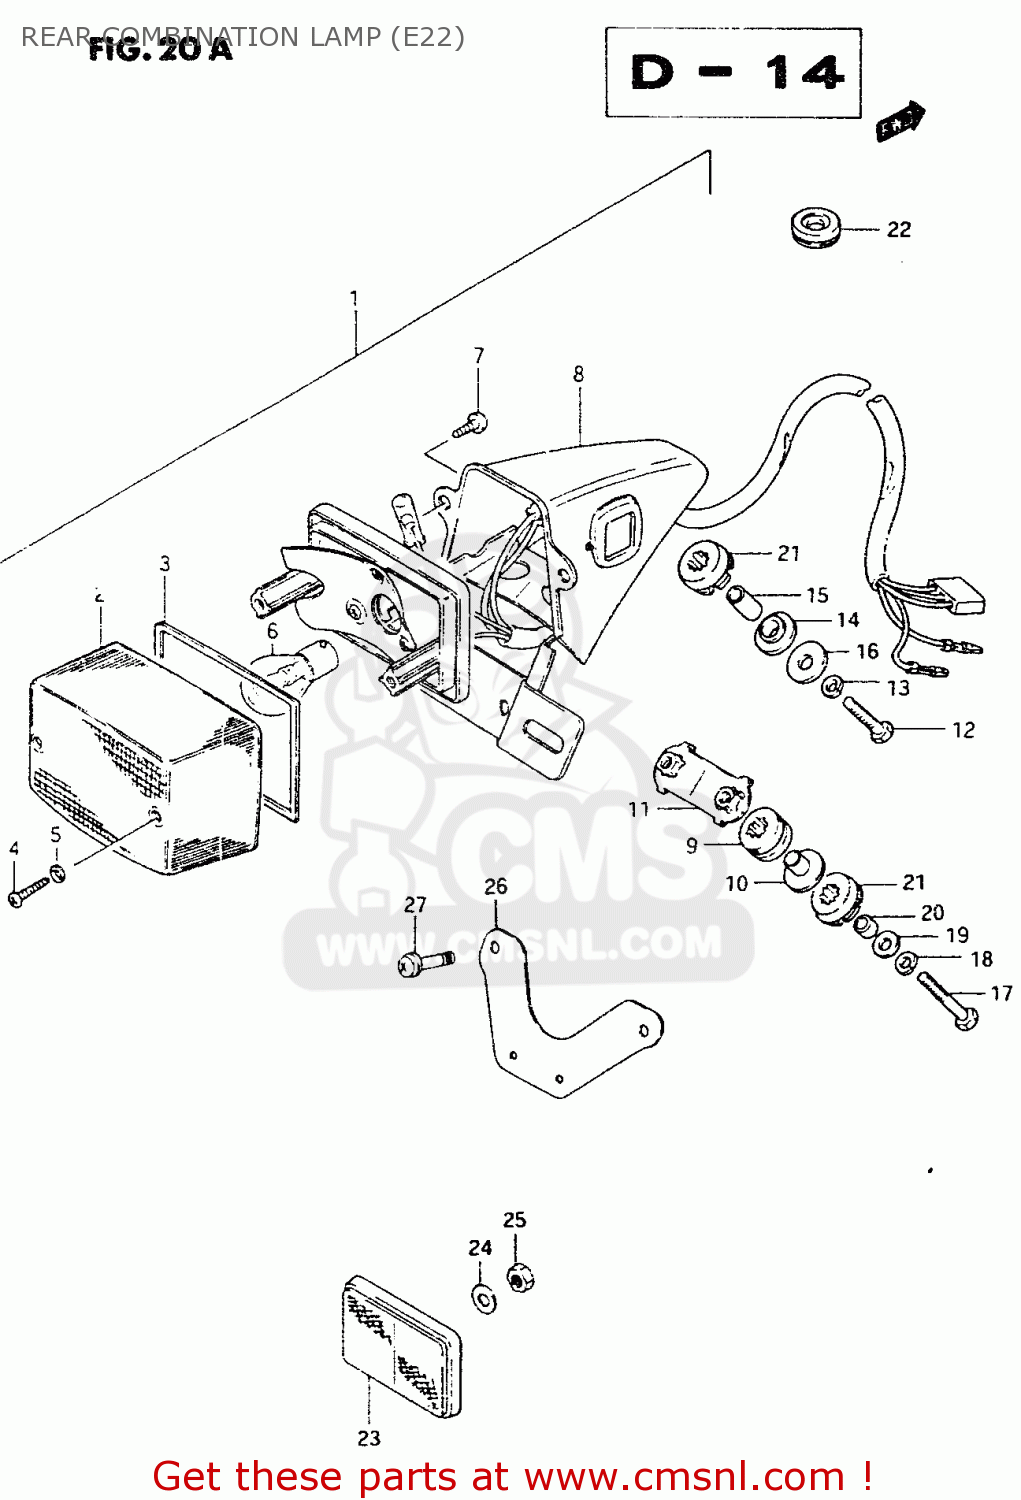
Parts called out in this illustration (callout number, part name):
1	LAMP UNIT, REAR COMBINATION
2	LENS
3	GASKET,RR COMBI LAMP LENS (NAS)
4	SCREW
5	GASKET (NAS)
6	BULB(12V21/5W)
7	SCREW
8	BRACKET UNIT,TAIL LAMP
9	CUSHION
10	SPACER
11	PLATE,RR COMBI
12	BOLT
13	WASHER,LOCK
14	CUSHION
15	SPACER (6.8X10X16)
16	WASHER (6.5X22X1.6)
17	BOLT
18	WASHER,LOCK
19	WASHER
20	SPACER (6.4X9X10.5)
21	CUSHION
22	GROMMET
23	REFLEX REFLECTOR,RR
24	WASHER
25	NUT
26	FLATE, LICENCE
27	SCREW
